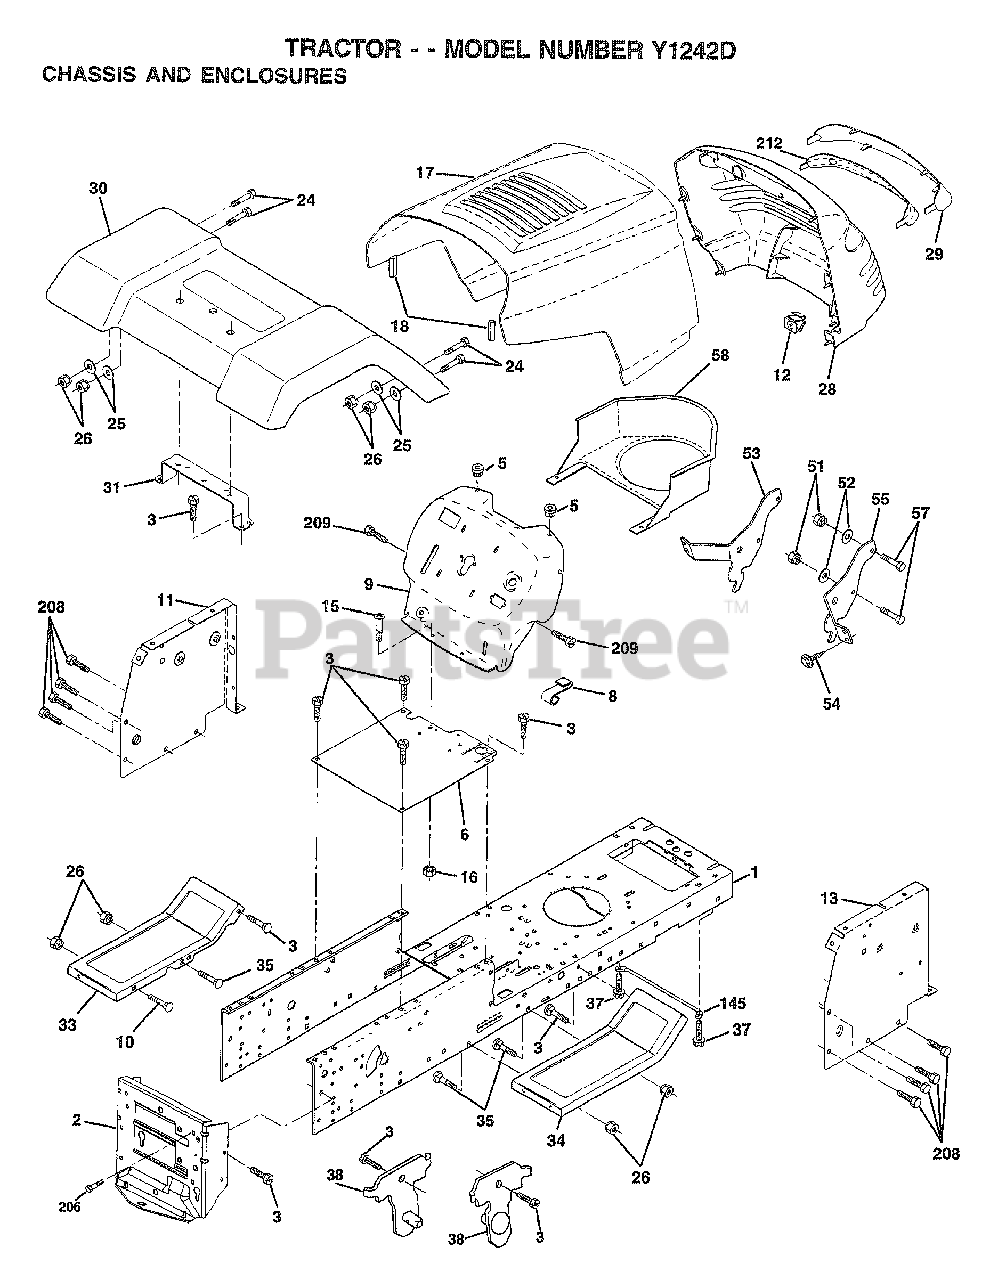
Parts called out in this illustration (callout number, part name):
2	DRAWBAR
3	SCREW
4	WASHER
5	BUMPER-HOOD/DASH
6	SADDLE-SILKSCREEN
8	CLIP.RETAINER
9	DASH
11	"PANEL-DASH,LH"
12	CLIP.TINNERMAN
15	SCREW
17	HOOD.STEEL.ASSY
24	BOLT
25	WASHER
26	NUT
28	GRILLE-MS428
29	LENS.GRILLE.PRIVATE LABEL
31	BRKT FENDER
33	FOOTREST.LH.LT/GT
34	FOOTREST.RH.LT/GT
35	BOLT
37	SCREW LT
38	BRKT ASM PIVOT MOWER REAR
51	NUT
52	WASHER
53	BRACKET.GRILLE.LH
54	SCREW.HEX.WS.HD
55	BRACKET.GRILLE.RH
58	AIR DUCT
145	"ROD POVOT,CHASSIS"
206	BOLT SHOULDER
208	SCREW
209	SCREW
